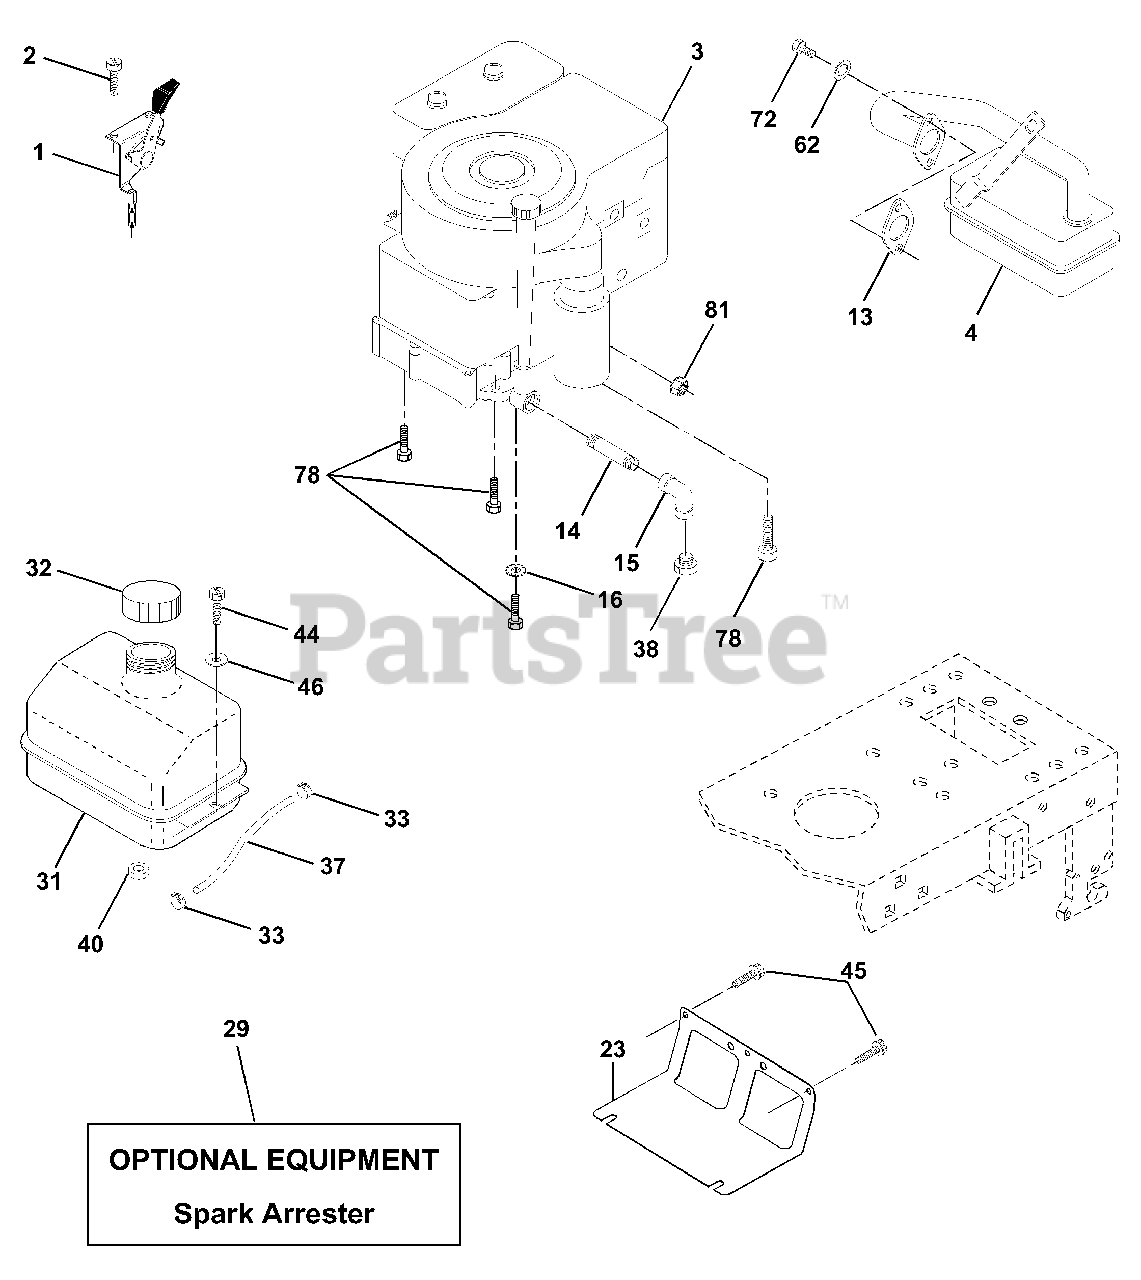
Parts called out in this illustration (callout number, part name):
1	Control Th/ch Flag
2	Screw Hex Thd Cut 1/4-20x5/8 T
4	Muffler Exhaust B&S Lc
13	Gasket Eng 1 313 Id Tin Plated
14	Nipple Pipe 3/8 Npt X 3"
15	Elbow Std 90 Degree 3/8-18 Npt
16	Washer Lock Ext Tooth 3/8
23	Shield BRN/DBR Guard
29	Kit Spark Arrestor (Flat Scrn)
31	Tank Fuel Front
32	Cap Asm Fuel
33	Clamp Hose
37	Line Fuel 20"
38	Oil Drain Plug
40	Bushing Snap Nyl Blk Fuel Line
44	Screw Thdrol 1/4-20 x 3/4
45	Screw Hex Wsh Thdrol 3/8-16
46	Washer 9/32 X 7/8 X 16 Ga
62	Washer Lock Hvy Hlcl Spr
72	Screw Hexcap 5/16-18 x 5/8
78	Screw 3/8-16 x 1-1/4
81	Nut Keps Hex 1/4-20 Unc
